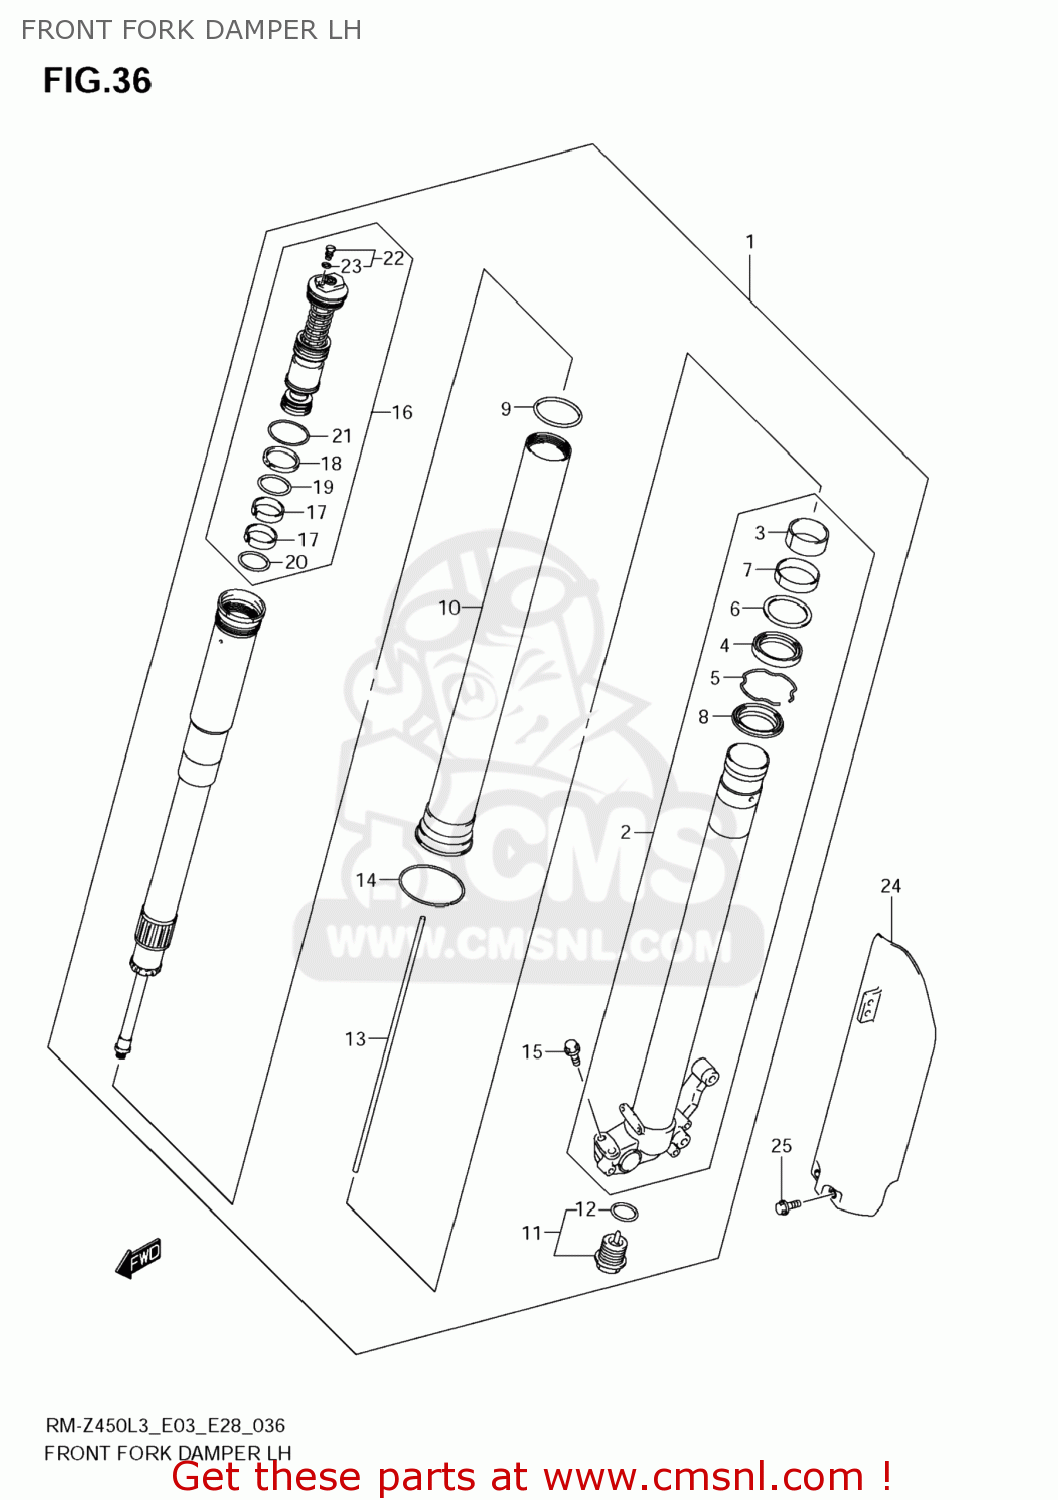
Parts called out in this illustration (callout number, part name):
1	DAMPER ASSY,FR FORK,L
2	TUBE,INNER,L
3	BUSH,SLIDE
4	SEAL,OIL
5	RING,OIL SEAL STOPPER
6	SPACER,SEAL
7	BUSH,GUIDE
8	SEAL,DUST
9	O RING
10	TUBE,OUTER
11	BOLT,CTR
12	O RING
13	ROD,PUSH
14	STOPPER,RING
15	BOLT
16	BOLT,FORK
17	BUSH, SLIDE
18	RING
19	O RING
20	O RING
21	O RING,FORK BOLT
22	BOLT,PLUG
23	O RING,PLUG
24	PROTECTOR,FR FORK,L
25	BOLT(6X10)
